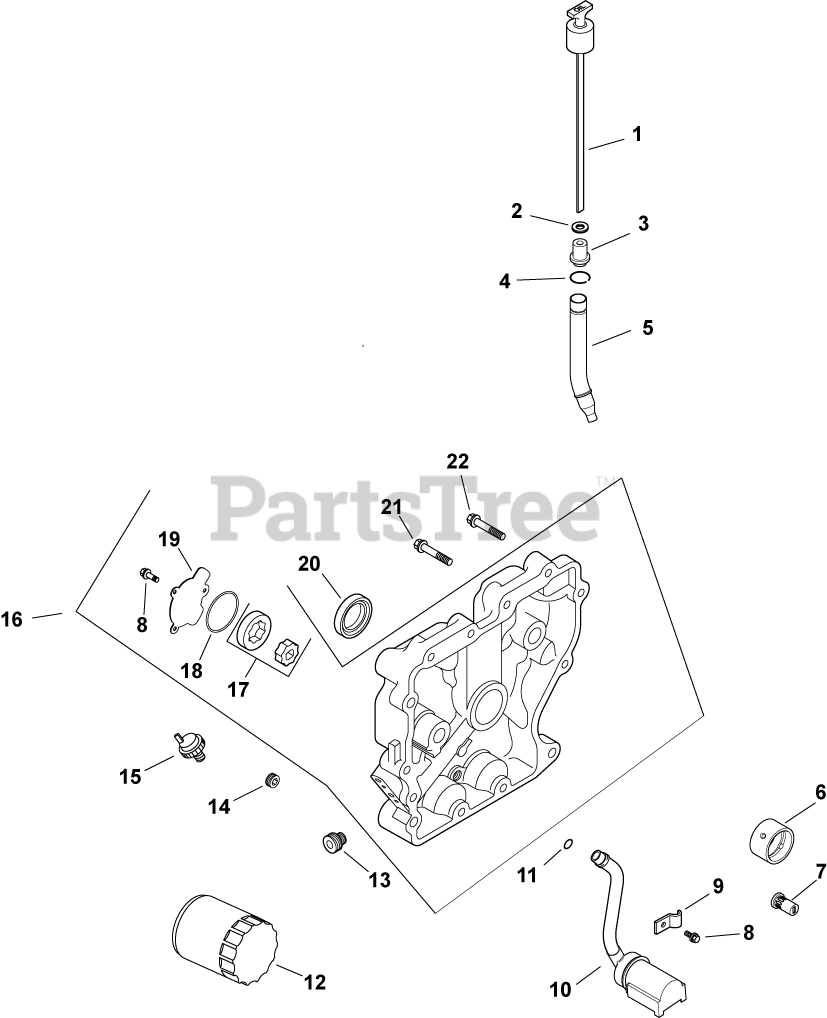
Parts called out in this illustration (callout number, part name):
1	DIPSTICK - DISCONTINUED
3	SEAL USE 25 032 13-S
5	TUBE, OIL FILL - DISCONTINUED
6	BEARING, CRANKSHAFT
7	VALVE, OIL PRESSURE RELIEF
8	SCREW,FLG THD FRM M5X0.8X16-(#25086398S)
10	KIT, OIL PICK-UP
11	O-RING (.5" DIA)
12	OIL FILTER
13	NIPPLE, OIL FILTER
14	PLUG, CTSK PIPE 1/8"
15	SENSOR, OIL PSI
16	PLATE, CLOSURE & BEARING
17	PUMP ASSEMBLY, OIL
18	O-RING (1.78" DIA)
19	COVER, OIL PUMP
20	SEAL, OIL
21	SCREW, FLG M8X1.25X45
22	SCREW, HEX FLANGE -USE 24 086 17-S
